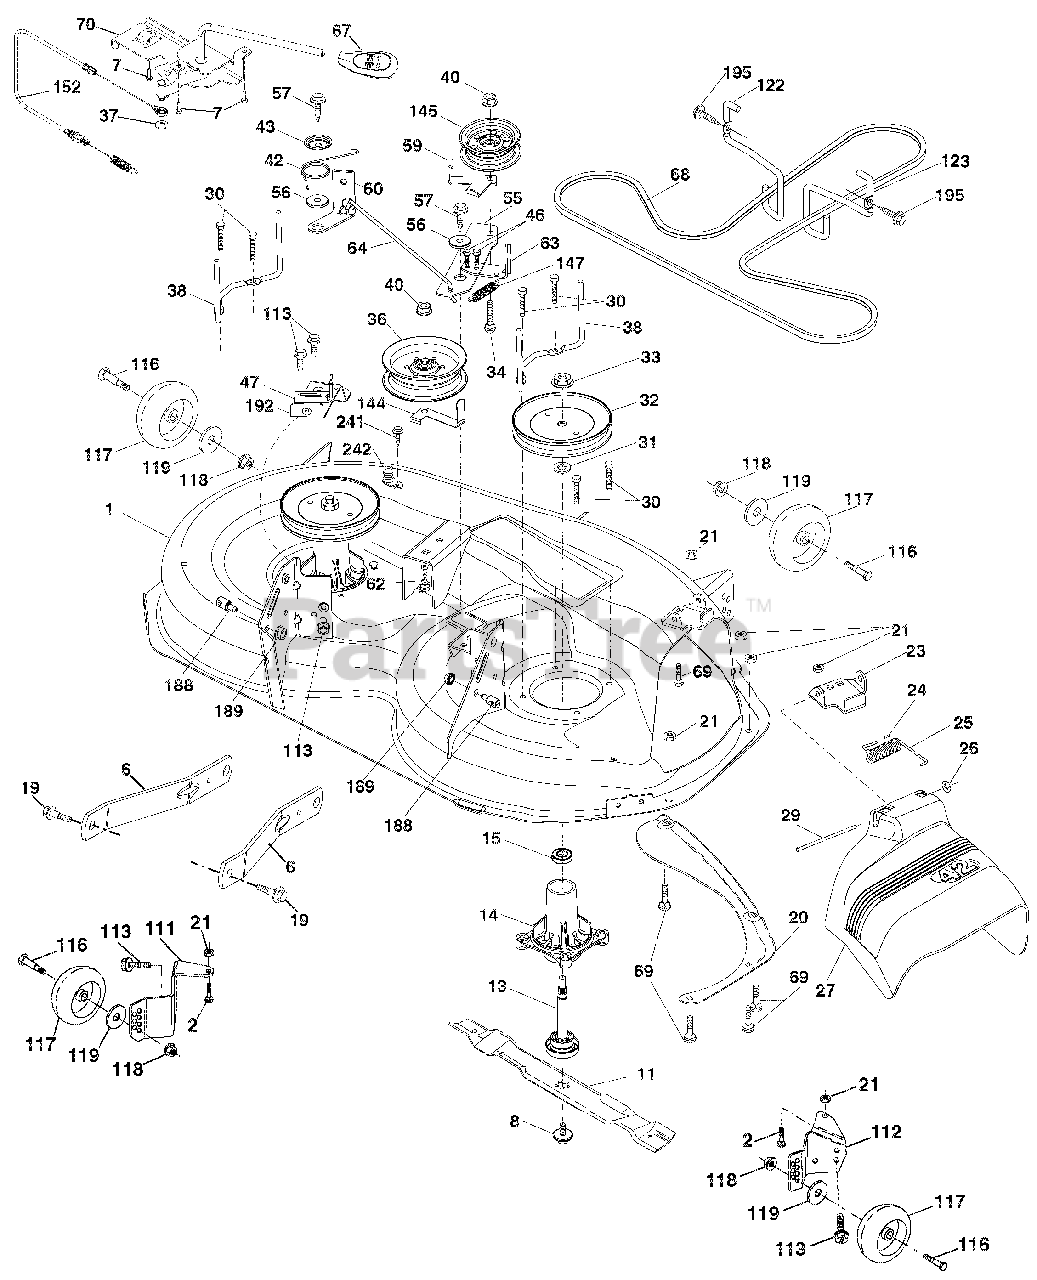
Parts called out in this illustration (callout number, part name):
1	DECK.PNT.WELDMENT.42"
1	DECK.SVC.46"HP.CC.4GWB.TEX.422
6	ARM.SUSPENSION.MOWER.REAR.LD
8	BOLT/WASHER ASM.7/16-20.UNF
11	BLADE.MOWER.42"HI LIFT PREMIUM
11	Blade 42SP" 3N1
11	Blade 42SP" 3N1 Premium
11	BLADE, HUSQ MULCH KIT
11	Blade Mulching 42 Premium (Fo
13	SHAFT ASM.MNDRL.N/GREASEABLE38
14	HOUSING.MANDREL.4PT.SERVICE
15	BEARING.BALL.MANDREL
19	BOLT.SHOULDER
20	BAFFLE.VORTEX.42.STD/HEAVY DTY
21	Nut, Hex, Crownlock 5/16-18
23	BRACKET.DEFLECTOR.38/42"2005
24	CAP.SLEEVE..80X.112.BLK.MOWER
25	SPRING.TORSION.DFL.38/42/46.GR
26	NUT.PUSH.PHOS.& OIL
27	SHIELD.DEFLECTOR.MOWER 42"BLK
29	ROD.HINGE.42/46"
30	SCREW.THD ROLL.DOD PT.HEX
31	WASHER.SPACER.MANDREL
32	PULLEY.MANDREL.5.438 PD.42"
32	MANDREL ASM.SUB.N-GRS.4 BOLT
32	PULLEY/NUT/WASHER AND BLADE BOLT/WASHERS NOT INCLUDED)
33	NUT.FLANGE.LOCK.TOP
34	BOLT.CARR.SH.3/8-16X1-1/2.GR5
36	PULLEY.IDLER.4.50.RAW
37	WASHER.13/32 X 13/16 X 16 GA.
38	KEEPER.BELT.LH.MANDREL.42/46"
40	Nut, Hex, Flangelock 3/8-16
42	SPRING.TORSION.BRAKE
43	SPRING.TORSION.RETAINER
46	SCREW.THD.ROLL.1/4-20 X 5/8
47	BRACKET.CLUTCH.CABLE
55	IDLER.ARM
56	SPACER.RETAINER
57	SCREW.3/8-16X1.SMGML.TAP/R.BLK
59	GUARD.TUV.IDLER
60	ARM.BRAKE.MOWER.42"
62	BOLT.RD.HD.SQ.NK.3/8-16UNC X 2
63	ARM.BRAKE.MOWER
64	LINKAGE.BRAKE
67	HANDLE.CLUTCH.CABLE.LT TEX.428
68	BELT.DRIVE.100.97"
69	BOLT.RDHD.SQNK.5/16-18 X 5/8
70	CLUTCH ASM.MANUAL.LT.TEX
111	BRACKET WHEEL GAUGE LH
112	BRACKET WHEEL GAUGE RH
113	BOLT.5/16-18HEX.WHS.HD.LCKSERR
116	BOLT.SHLD."A"2.41."B"1.66
117	WHEEL.GAGE.HALF.SPOKED
118	Nut, Hex, Flangelock 3/8-16
119	Washer 3/8 x 7/8 x 14 Ga.
122	KEEPER.BELT.ENGINE.LH.LT.TEX
123	KEEPER.BELT.ENGINE.RH.LT.TEX
144	KEEPER.BELT.MOWER
145	PULLEY.IDLER 48"PRIMARY
147	SPRING.RETURN.DECK.38/46"
152	CABLE.CLUTCH.MANUAL.W/SPR.
188	STUD.FASTNER.W/'D'ANTI-ROTATIO
189	Nut, Lock Hex Flange 5/16-18 u
192	BRACKET.BRAKE.STAND.LH
195	SCREW.HEXWSH THDR3/8-16X3/4.BL
242	PORT WASHOUT
